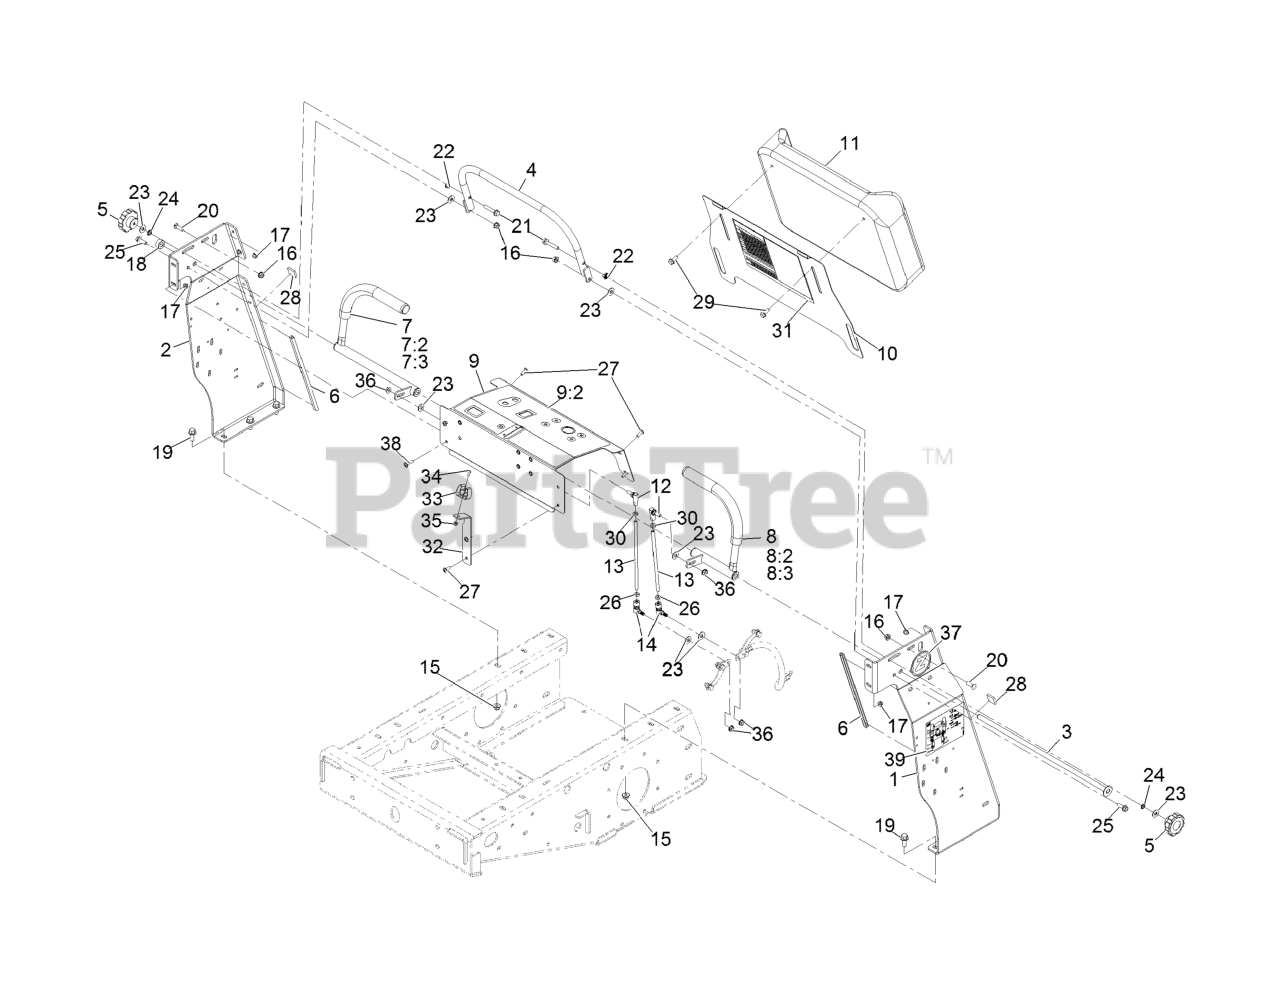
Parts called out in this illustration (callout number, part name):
1	Upright-Tower, Lt [blk-Txt]
2	Upright-Tower, Rt [blk-Txt]
3	Rod-Pivot, Joy Stick
4	Bar-Speed [blk-Txt]
5	KNOB-FLUTED
6	STRIP-TRIM, 12.0"
7	Stick-Joy, Rt
7:2	GRIP-CONTROL, MOTION
7:3	BUSHING-FLANGE
8	Stick-Joy, Lt
8:2	GRIP-CONTROL, MOTION
8:3	BUSHING-FLANGE
9	ASM-PANEL, CONTROL
9:2	Decal-Control Panel
10	PLATE-PAD, KNEE
11	PAD-KNEE, Z-LOGO
12	Balljoint-SS
13	ROD-CONTROL, MOTION
14	Ball Joint-Quick Disconnect, SS
15	Nut-Hex Flange
16	Nut-Hex Flange
17	Nut-Hex Flange
19	SCREW-HHF
20	Bolt,Carriage,5/16-18X1,ST/ST 18-8
21	Screw-HHF
22	Nut,Hex Flange,5/16-18,Sst, Rie2006
23	FLAT WASHER, 5/16 NOM,ST
24	Washer-Lock
25	SCREW-HHF
26	Nut-Hex
27	Screw-Hsbhf
29	SCREW-HHF
30	Nut-Hex
31	Decal-Spray Chart
32	Mount-Gun
33	Holder-Tool, Clip
34	Screw-HSBH
35	Nut-Hex Flange
36	Nut-HHF
37	Decal-Z-Logo
38	Screw-Hsbhf
39	Decal-Service Aid
